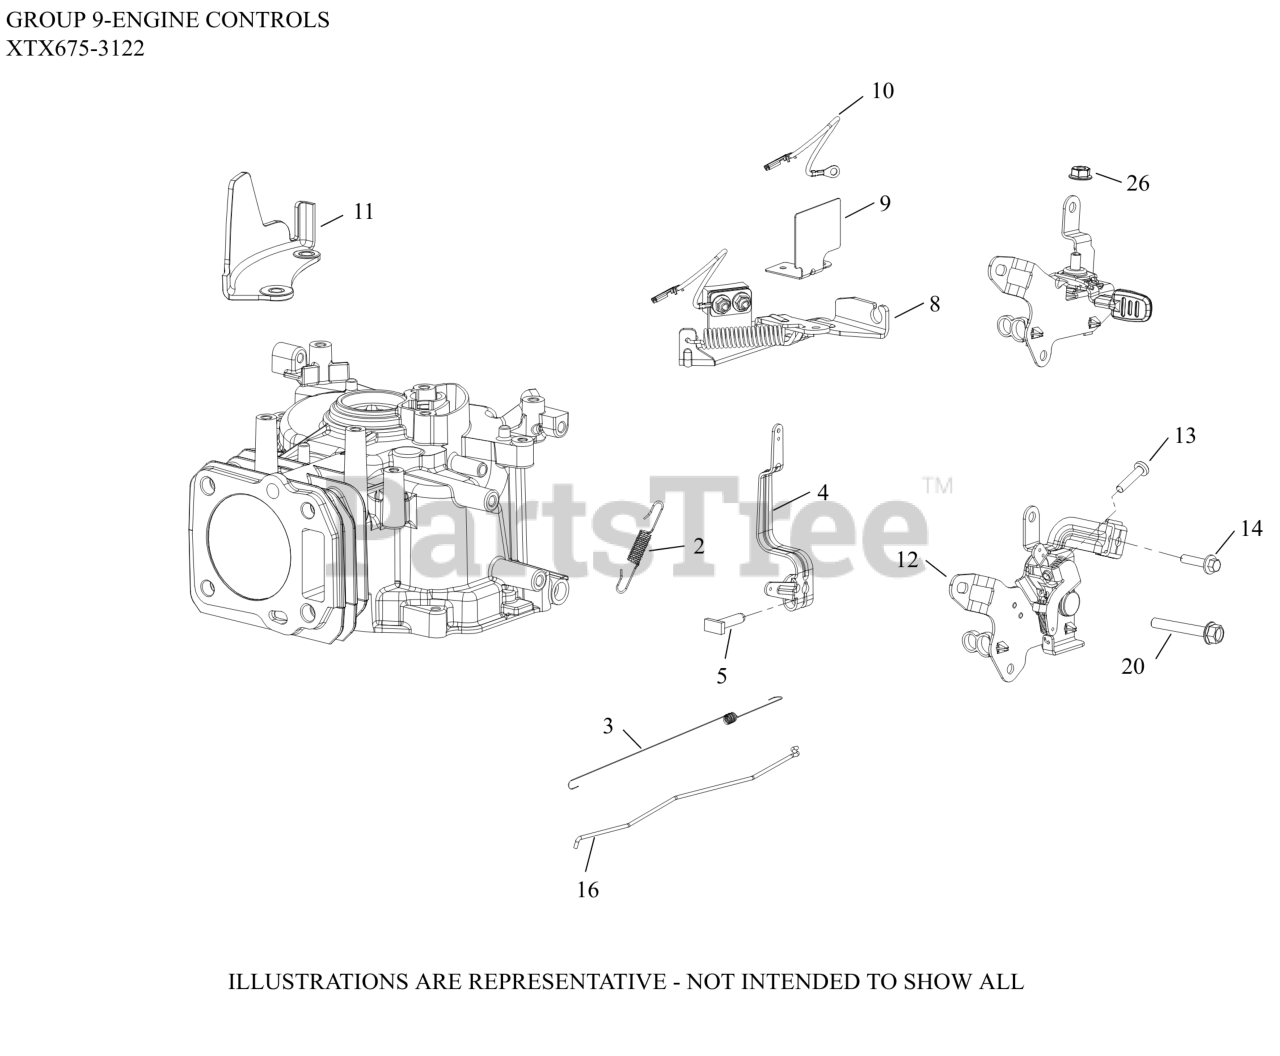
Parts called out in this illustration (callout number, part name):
2	SPRING, GOV (2800-3300 RPM)
3	SPRING, LINKAGE
5	SCREW, RECTANGLE HEAD (M6)
8	BRAKE ASSEMBLY
9	GUARD, BRAKE - USE 14 314 30-S
10	LEAD, KILL (BRAKE TO IGN. MODULE)
11	GUARD, FINGER
12	CONTROL ASSEMBLY (VAR. SPEED)
13	SCREW, #25 6-LOBE PAN HD (M5)
14	SCREW, (M5) HEX FLANGE
16	LINKAGE, GOVERNOR-(#1407927S)
20	SCREW, HEX FLANGE (M6)
26	NUT, HEX FLANGE LOCK (M6)
34	LEVER, GOVERNOR
